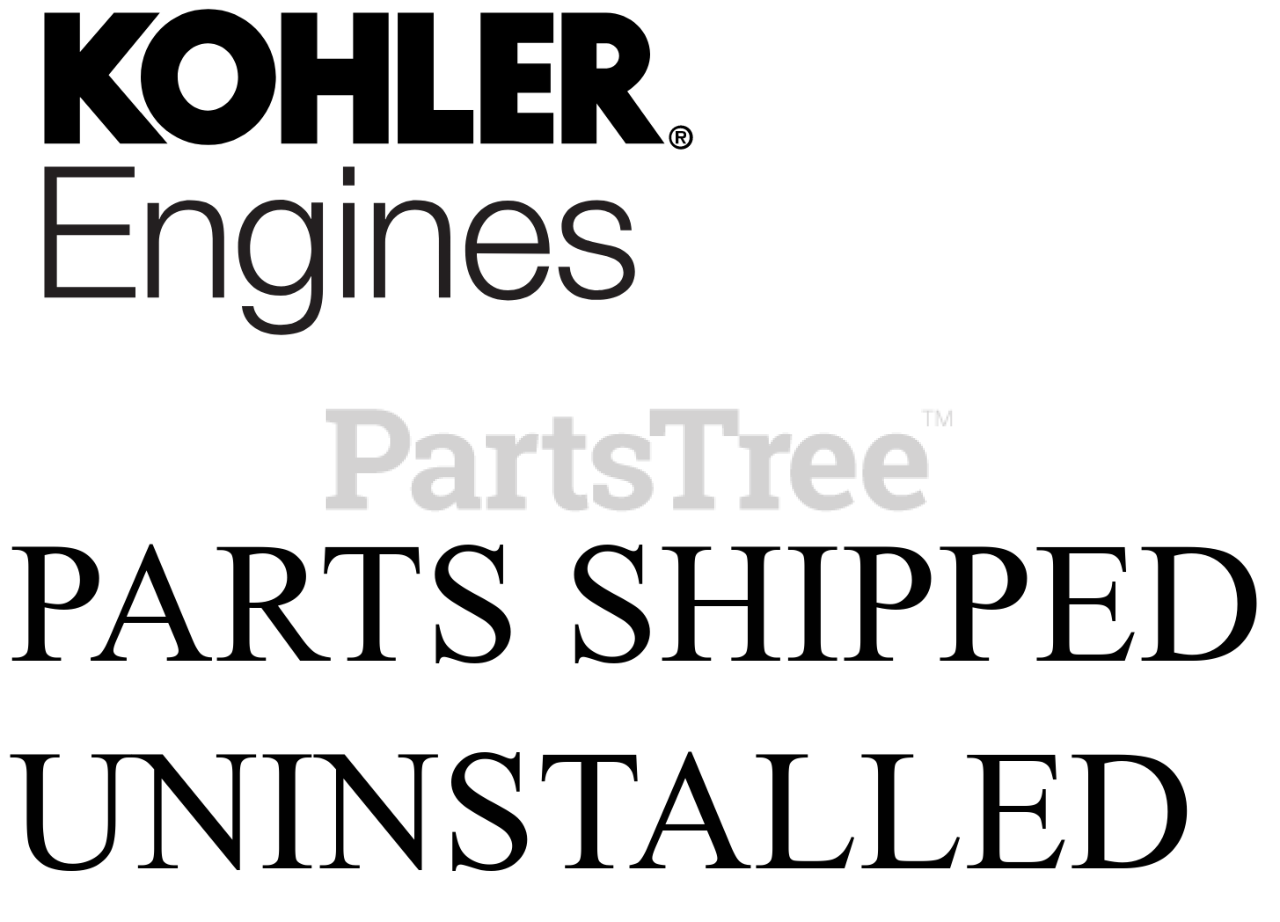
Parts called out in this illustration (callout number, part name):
NI	BRACKET, SUPPORT - USE 20 126 18-S
NI	KIT, MUFFLER GUARD
NI	KIT, MUFFLER (REPLACEMENT)
NI	SCREW, HEX SOCKET HEAD CAP
NI	SCREW, FLG THD FRM M5X.8X10
NI	SCREW,FLG THD FRM M6X1.0X16-(#25086397S)
NI	WASHER, SPRING LOCK 5/16"
